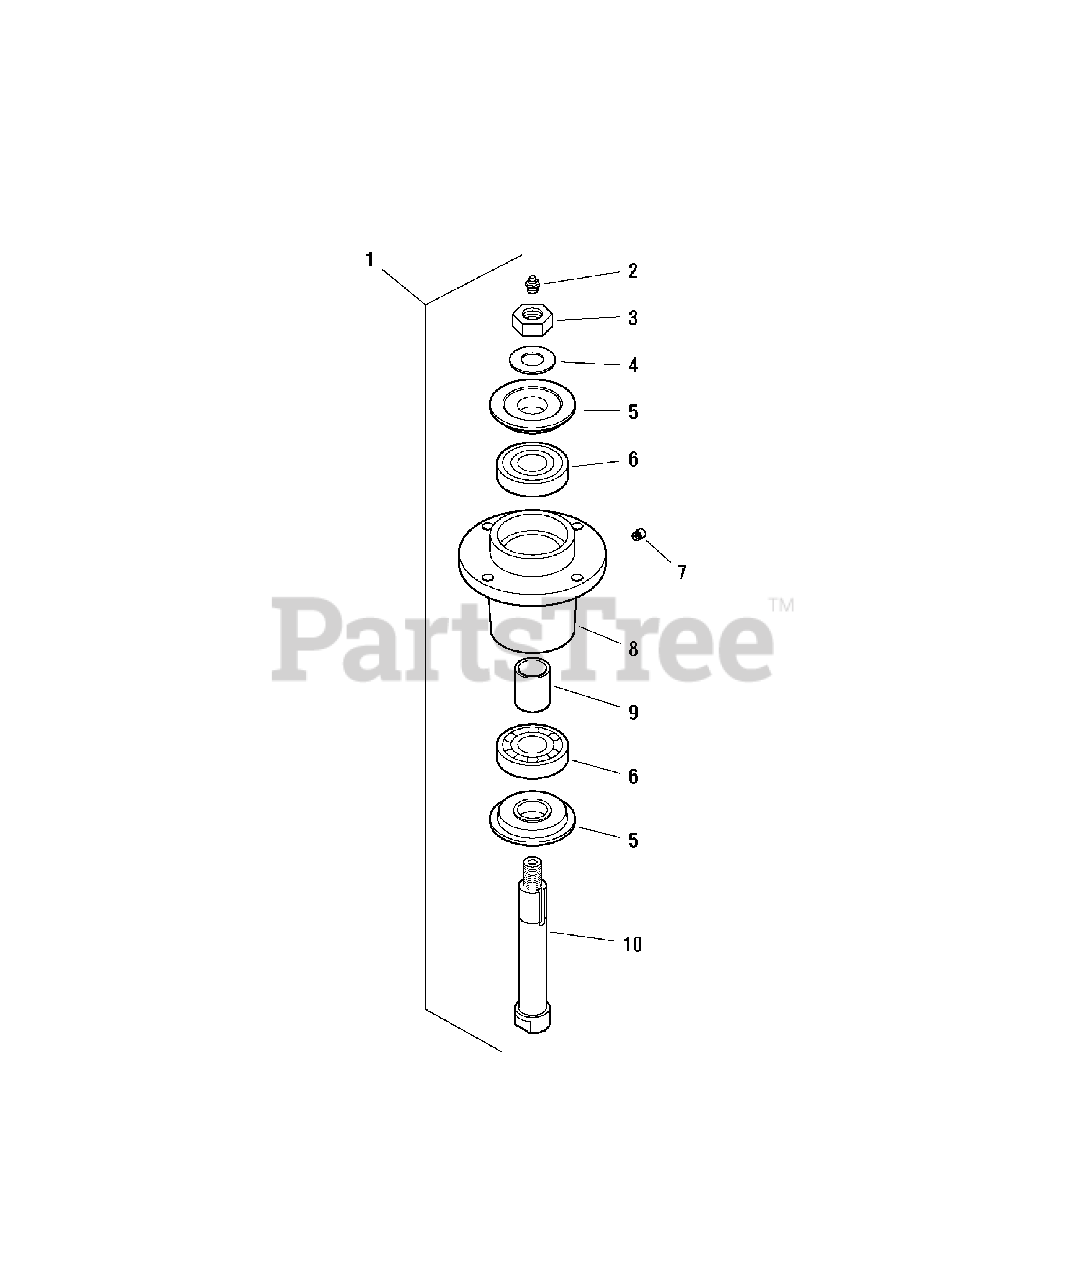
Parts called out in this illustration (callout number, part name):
1	SPINDLE ASSEMBLY, Complete (Includes Ref No. 2 - 10)
2	GREASE FITTING
3	NUT, 3/4-16 Hex
4	WASHER, 3/4" Belleville
5	TRASH SHIELD
7	RELIEF VALVE
8	SPINDLE HOUSING
9	SPACER, 1.00 x 1.25 x 1.75
10	SPINDLE SHAFT
